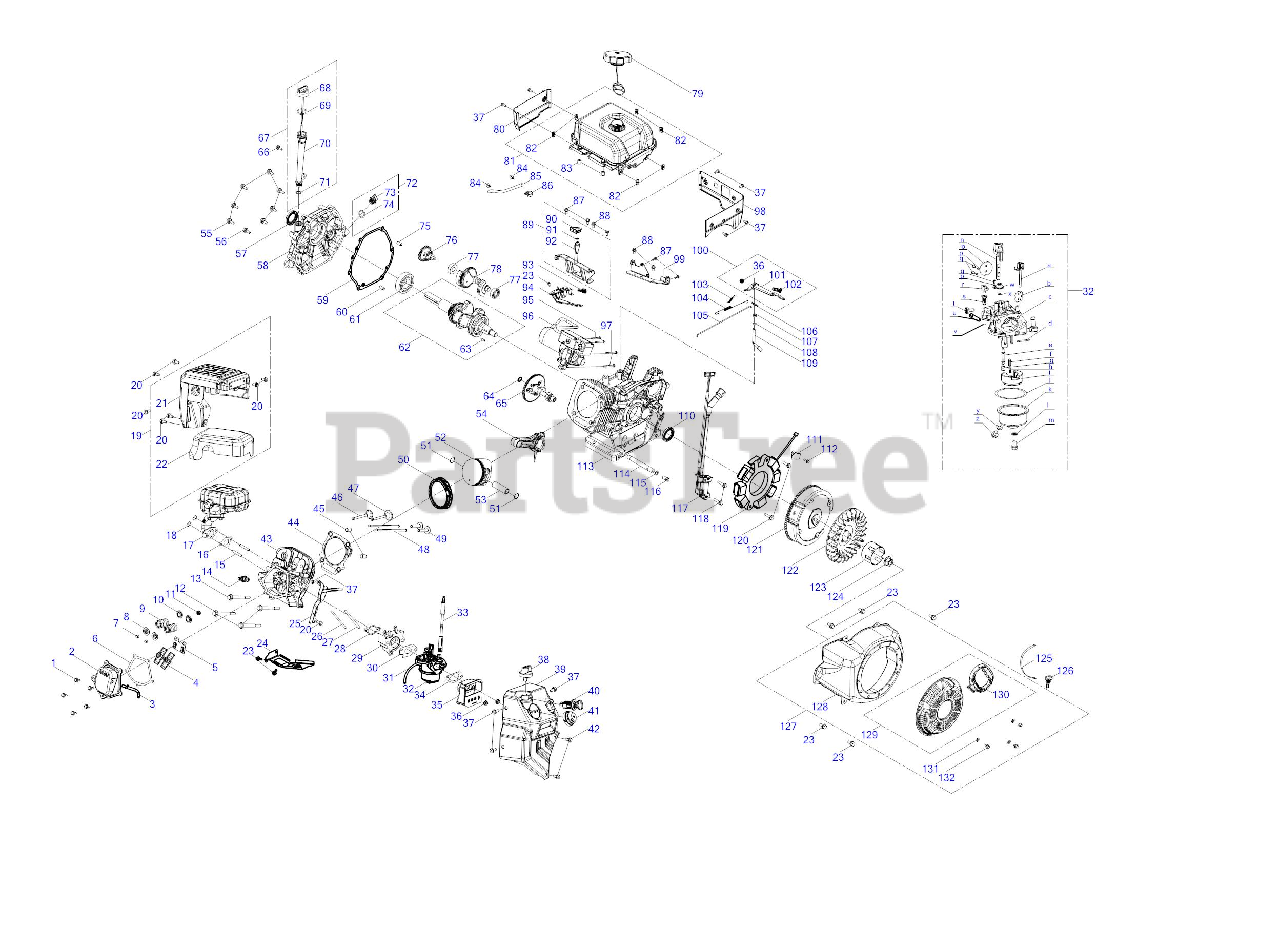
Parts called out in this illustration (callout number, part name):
1	BOLT M6-1 x 16 GR8.8
2	VALVE COVER
3	BREATHER HOSE
4	ROCKER ARM ASSEMBLY
5	PUSH ROD GUIDE
6	VALVE COVER GASKET
7	EXHAUST VALVE ADJUSTMENT
8	EX VALVE SPRING RETAINER
9	VALVE SPRING
10	VALVE SPRING RETAINER
11	INTAKE VALVE SEAL
12	SCREW M10-1.25 x 87 x GR10.9
13	SCREW M10-1.25 x 65 x GR10.9
14	SPARK PLUG
15	STUDS M8-1.25 x 48.5
16	MUFFLER GASKET
17	MUFFLER
19	MUFFLER SHIELD ASSEMBLY
20	BOLT M6-1 x 10 GR8.8
21	Muffler Shroud
22	Muffler Inner Shield
23	BOLT M6-1 x 12 GR8.8
24	CYLINDER BAFFLE
25	RECOIL SNOW GUARD
27	STUD
28	CARBURETOR INSULATOR GASKET
29	CARBURETOR INSULATOR
30	CARBURETOR INSULATOR GASKET
31	PRIMER HOSE
32	CARBURETOR ASSEMBLY HY-190W
33	CHOKE KNOB SHAFT
34	HEATER BOX CARBURETOR GASKET
35	HEATER BOX
37	BOLT M6-1 x 14 GR8.8
38	CHOKE LEVER
39	CONTROL PANEL
40	ENGINE KEY SWITCH ASSEMBLY
42	SCREW M6-1 x 20 CL5.8
43	CYLINDER HEAD ASSEMBLY
44	CYLINDER HEAD GASKET
46	EXHAUST VALVE
47	INTAKE VALVE
48	PUSH ROD
49	TAPPET
50	PISTON RING KIT
51	PISTON PIN SNAP
53	PISTON PIN
54	CONNECTING ROD
55	SCREW M8-1.25 x 38 GR10.9
56	BOLT M8 x 45
57	OIL SEAL
58	CRANKCASE COVER
59	CRANKCASE COVER GASKET
61	BALL BEARING
62	CRANKSHAFT ASSEMBLY
63	FLYWHEEL KEY
65	CAMSHAFT ASSEMBLY
66	BOLT M6-1 x 18 GR8.8
67	OIL DIPSTICK ASSEMBLY
68	OIL DIPSTICK INDICATOR
69	DIPSTICK O-RING
70	OIL DIPSTICK TUBE
72	OIL DRAIN PLUG ASSEMBLY
75	DOWEL PIN
76	GOVERNOR GEAR/SHAFT ASSEMBLY
77	BALL BEARING
78	BALANCE GEAR ASSEMBLY
80	FUEL TANK BACK PANEL
81	FUEL TANK ASSEMBLY
82	THREADED TAB
84	HOSE CLAMP
86	FUEL LINE SUPPORT CLAMP
88	BOLT M8-1.25 x 14 GR8.8
89	FUEL TANK MOUNTING BRACKET
90	RUBBER GROMMET
91	RUBBER GROMMET
92	FUEL TANK MOUNTING BRACKET
93	THROTTLE KNOB
94	THROTTLE CONTROL
96	ELECTRIC STARTER
97	BOLT M8-1.25 x 55 GR8.8
98	FUEL TANK FRONT PANEL
99	FUEL TANK BASE BRACKET
100	GOVERNOR ARM ASSEMBLY
101	GOVERNOR ARM BRACKET
102	BOLT M6-1 x 21
103	GOVERNOR SPRING
104	IDLE SPRING
105	GOVERNOR ROD
106	GOVERNOR SHAFT CLIP
107	GOVERNOR SEAL
108	FLAT WASHER
109	GOVERNOR SHAFT
110	OIL SEAL
111	ALTERNATOR WIRE
112	BOLT M6-1 x 8 GR8.8
113	CRANKCASE COMPLETE
114	OIL DRAIN PIPE
115	WASHER
116	OIL DRAIN PLUG
117	IGNITION MODULE
118	IGNITION COIL BOLT M6-1 x 28 GR8.8
119	ALTERNATOR
120	BOLT-M6-1 x 30 GR8.8
121	ENGINE FLYWHEEL
122	COOLING FAN
123	STARTER CUP
124	FLYWHEEL NUT M16X1.5
126	IGNITION KEY
127	BLOWER HOUSING ASSEMBLY
128	BLOWER HOUSING
129	RECOIL ASSEMBLY
130	STARTER HANDLE
131	RECOIL FLAT WASHER
132	BOLT M6 x 10
